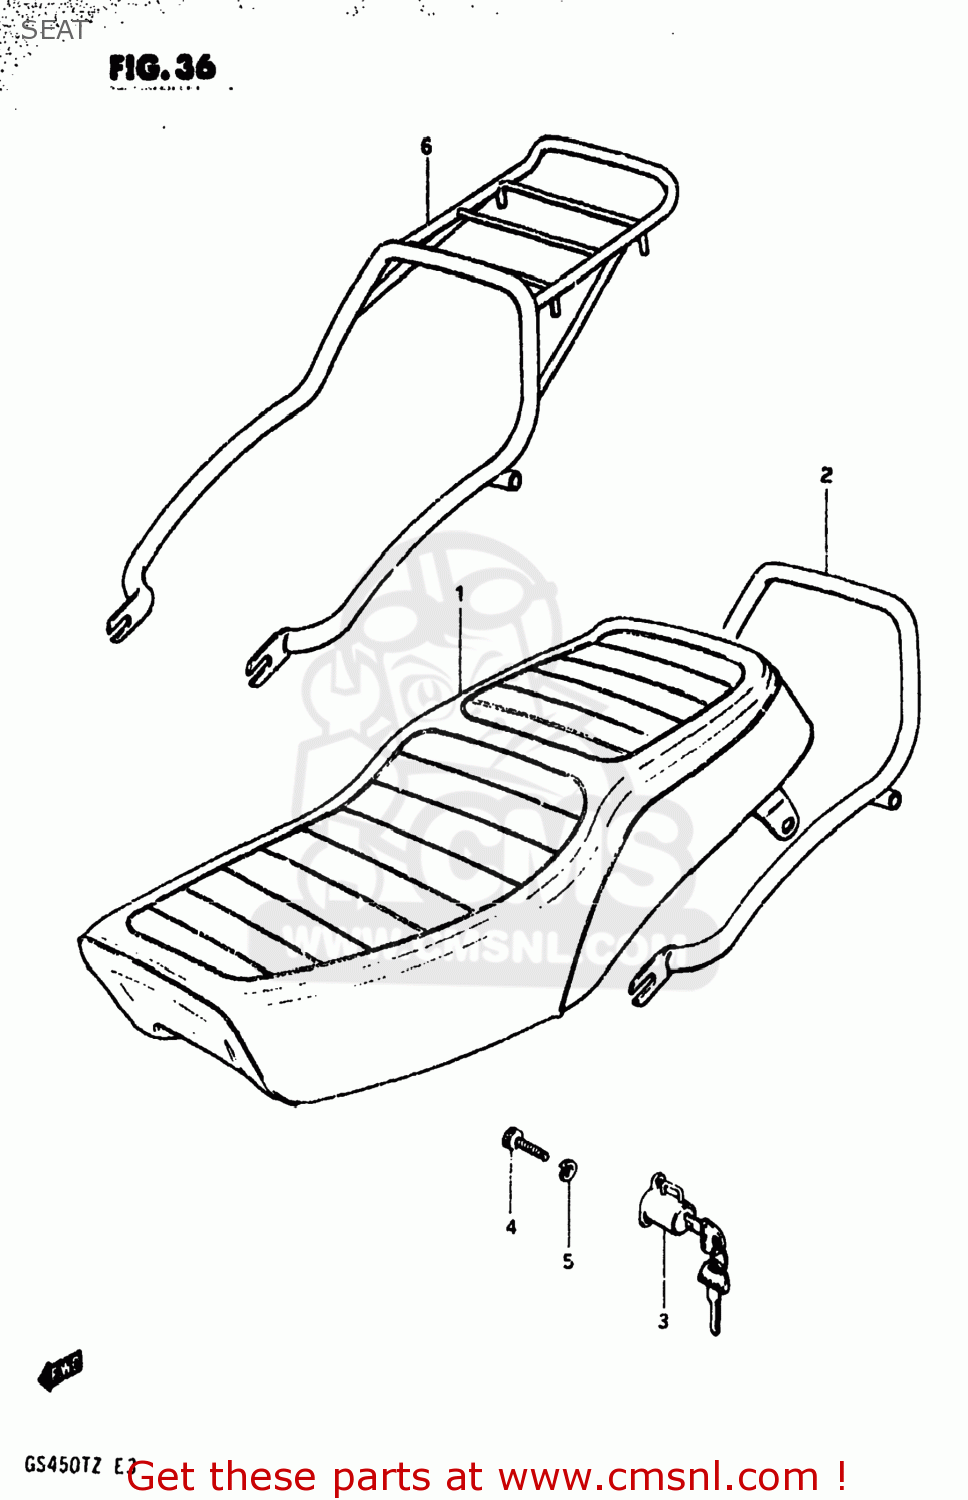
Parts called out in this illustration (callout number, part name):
1	SEAT ASSEMBLY
2	HANDLE,PILLION RIDER
3	LOCK ASSEMBLY,HELMET
4	BOLT 6X11
5	LOCK WASHER
6	CARRIER
